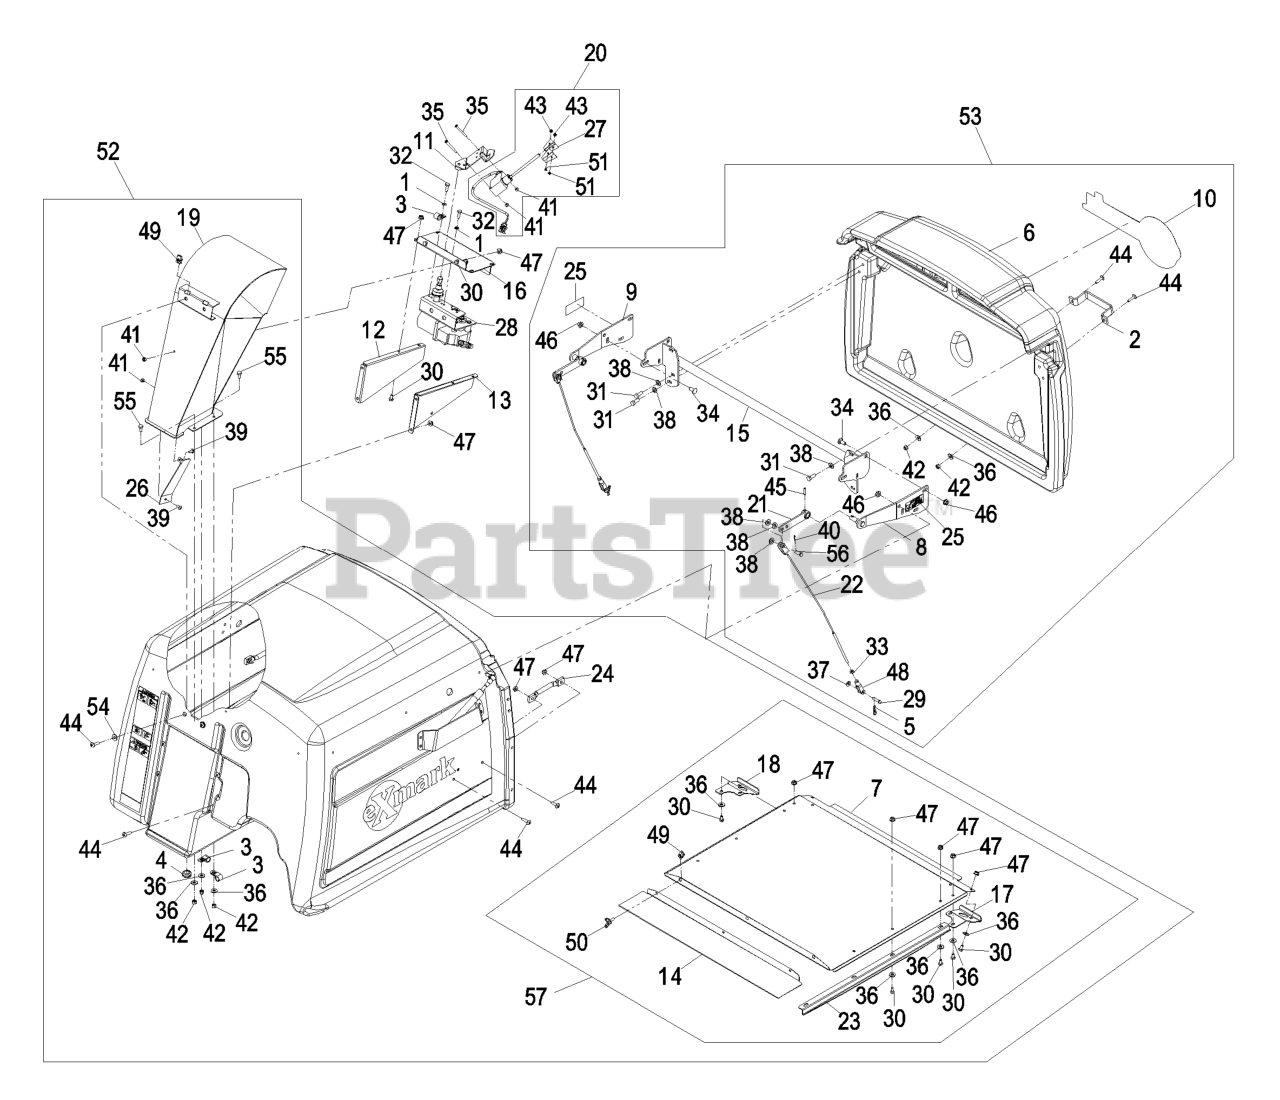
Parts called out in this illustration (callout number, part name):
1	WASHER-SPRING
3	CLIP-LOOM
4	GROMMET
5	PIN-COTTER
7	PANEL-SCREEN, HOPPER
10	DECAL,EXMARK LOGO
12	BRACKET-DRIVE MOTOR, LH
13	BRACKET-DRIVE MOTOR, RH
14	PANEL-SCREEN, REMOVABLE
16	PLATE-SWITCH
17	HANDLE-SCREEN, LH
18	HANDLE-SCREEN, RH
20	ASM,FILL SENSOR
21	ARM-DOOR
22	CABLE ASM
23	GUIDE-SCREEN
24	GUIDE-CABLE
25	DECAL-PINCH POINT
26	DEFLECTOR-DISCHARGE CHUTE
27	FLAG- SENSOR, FILL
28	MOTOR WIRING ASM
30	SCREW-HH
31	SCREW-HH
32	SCREW-HH
33	NUT-JAM
34	SCREW-CARR
35	SCREW-PPH
36	WASHER-FLAT
37	WASHER-FLAT
38	WASHER-PLAIN
39	SCREW-PTH
40	PIN-COTTER
41	NUT-LOCK, NI
42	NUT-LOCK, NI
43	NUT-HEX
44	SCREW-PTH
45	PIN-ROLL, SLOTTED
49	Nut, Retainer-Panel 1/4-20
51	SCREW-PAN
52	ASM,HOPPER
53	ASM,DOOR HOPPER
55	SCREW-HH
56	PIN-CLEVIS
57	HOPPER SCREEN ASM
